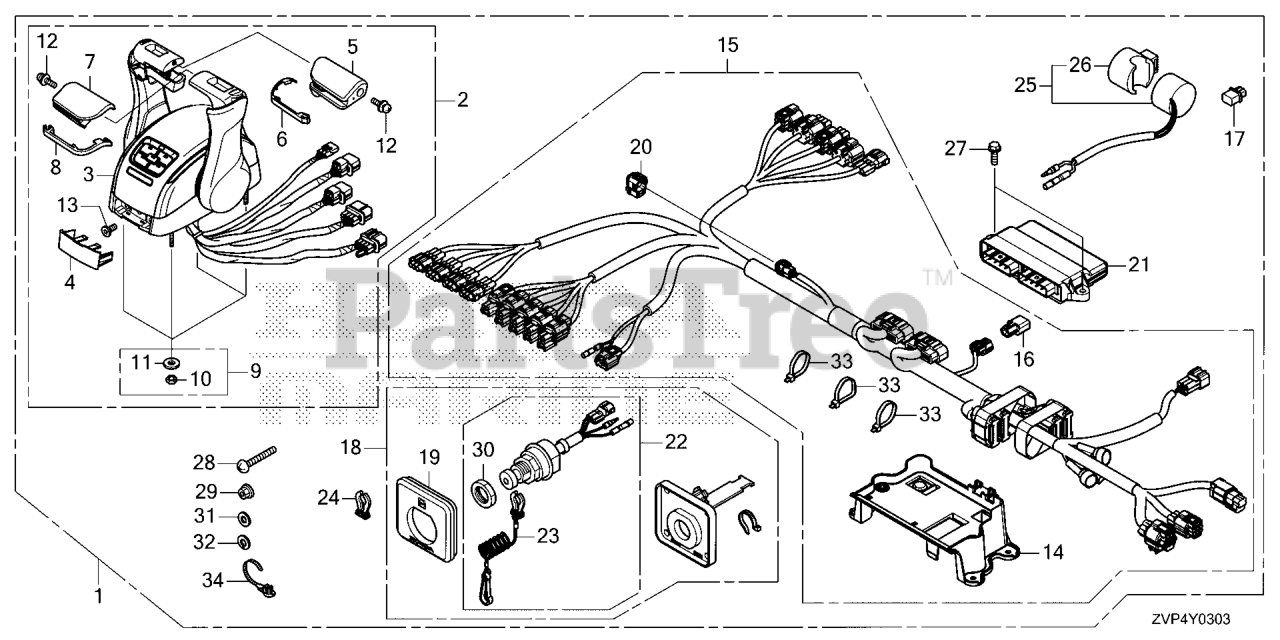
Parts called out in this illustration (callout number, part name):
1	BOX KIT (TWIN-2ND)
1	BOX KIT, R/C (2ND)
2	BOX ASSY., REMOTE CONTROL (TOP MOUNT DUAL)(RH)
3	CONTROL HEAD
4	COVER CAP
5	GRIP
6	GRIP PLATE
7	GRIP
8	GRIP PLATE
9	NUT SET, MOUNTING
10	NUT
11	WASHER
12	PAN HEAD SCREW
13	SOCKET HEAD CAP SCRE
14	CASE, CONTL UNIT
15	CASE (TWIN-2ND)
15	CASE ASSY. (2ND)
16	TERMINATOR ASSY.
17	DUMMY, WATERPROOF CONNECTOR
18	PANEL ASSY., EMERGENCY STOP
19	PANEL, EMERGENCY STOP SWITCH
20	CAP, DUMMY (WPC 4P 090 M) (RED)
21	UNIT ASSY., CONTL
22	SWITCH ASSY., EMERGENCY STOP
23	WIRE, EMERGENCY
24	CLIP, EMERGENCY LOCK
25	BUZZER ASSY., WARNING
26	SUSPENSION, WARNING BUZZER
27	BOLT, FLANGE (6X20)
28	SCREW, PAN (5X40) DUAL QTY = (8) (SINGLE)
29	NUT, FLANGE (5MM)
30	NUT
31	WASHER, PLAIN (5MM)
32	WASHER, SPG (5MM)
33	BAND, SELF-LOCK Use from Frame SN 3000253.
34	CLIP, BAND HARNESS (152.4MM) (BLACK)
